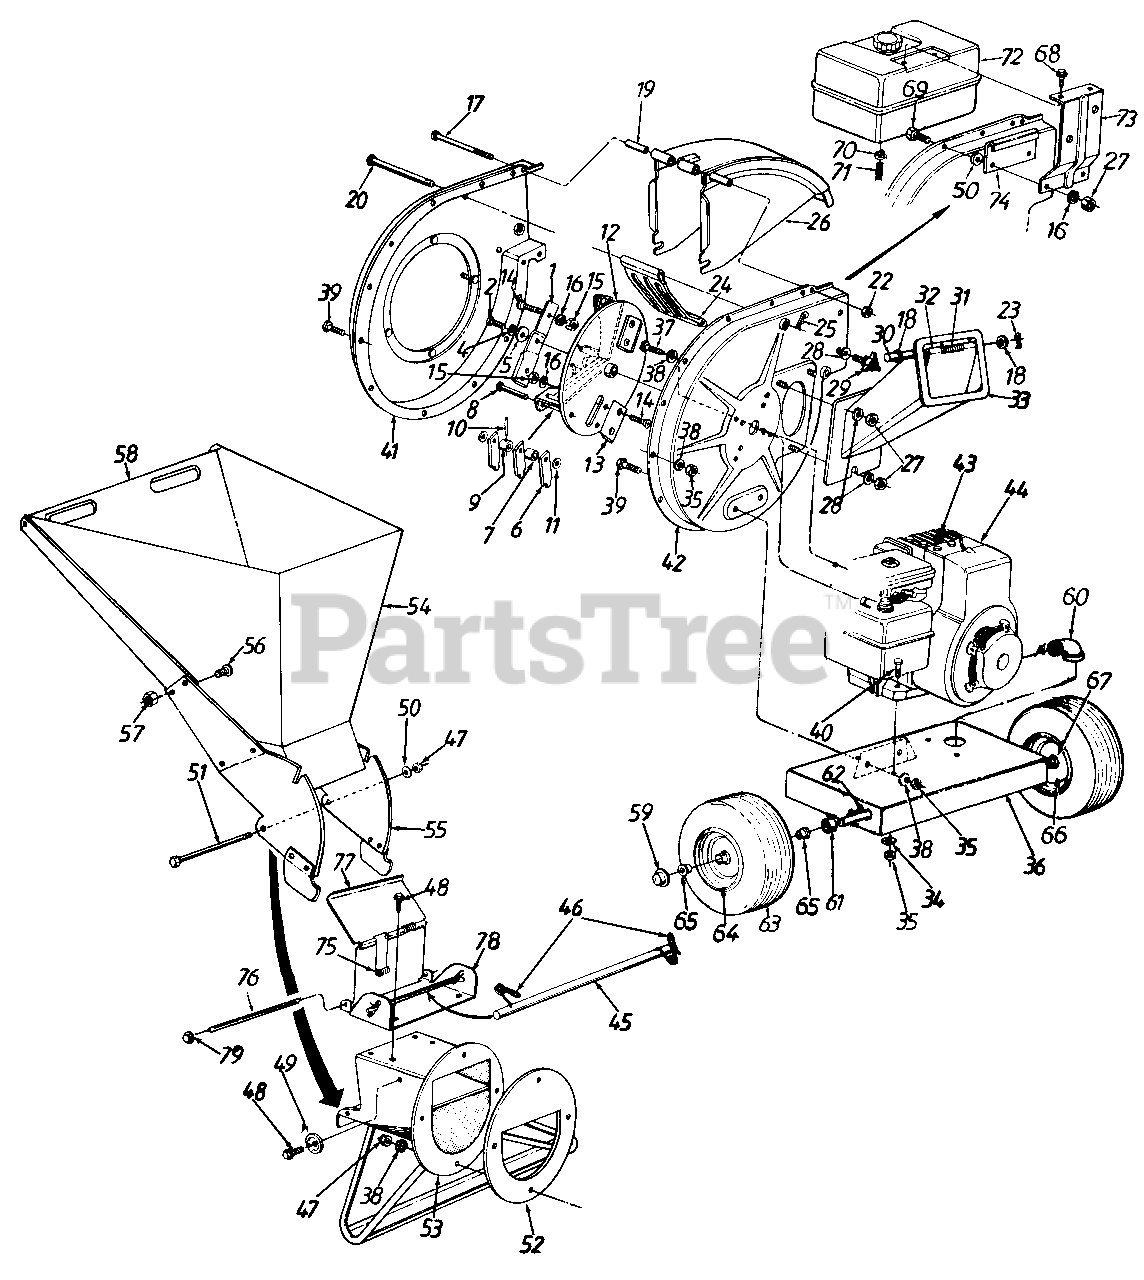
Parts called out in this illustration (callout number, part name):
1	Blade
2	Hex Patch Bolt 3/8-24 x 2.25" (Gr. 8)
4	L-Wash. 3/8" I.D. H.D.
5	Fl-Wash. .406" I.D. x 1.25" O.D. Hdn.
6	Flail
7	Flail Spacer
8	Clevis Pin .496" Dia.
9	Flail Spacer w/.160" Dia. Hole
10	Spring Roll Pin 1.12" Lg.
11	Fl-Wash. .531" I.D. x .94" O.D.
12	Impeller Ass'y. Comp.
13	Chipper Blade
14	Flat Hd. Scr. 5/16-24 x .75" Lg.
15	Hex Top L-Nut 5/16-24 (Gr. 5)
16	L-Wash. 5/16" I.D.
17	Hex Bolt 1/4-20 x 3.75" Lg.
18	Fl-Wash. .281" I.D. x .5" O.D.
19	Chute Hinge Spacer 1.66" Lg.
20	Clevis Pin .5" Dia. x 4.62" Lg.
22	Hex Ctr. L-Nut 1/4-20 Thd.
23	Cotter Pin
25	Internal Cotter Pin 3/8" Dia.
27	Hex Nut 5/16-18 Thd. (Gr. 5)
28	Bell-Wash. .345" I.D. x .88"
29	Hand Knob
30	Chipper Door Rod
31	Torsion Spring 1.14" Lg.
35	Hex Nut 5/16-18 Thd. (Gr. 5)
37	Hex Bolt 5/16-24 x .75" Lg.
38	L-Wash. 5/16" I.D.
39	Hex Bolt 5/16-18 x .75" Lg. (Gr. 5)
40	Hex Bolt 5/16-18 x 1.75" Lg.
44	Engine
45	Release Bar
46	Torsion Spring 1.06" Lg.
47	Elastic Lock Nut 5/16-18 Thd.
48	Hex Wash. Hd. Self-Tap Scr. 5/16-18 x .75" Lg.
49	Stop Washer
50	Fl-Wash. 5/16" I.D.
51	Hex Bolt 5/16-18 x 8.38" Lg.
57	Hex L-Nut 1/4-20 Thd.
60	Drain Elbow (645C)
61	Spacer .64" I.D. x .38" Lg.
62	Shredder Axle
66	Air Valve
67	Grease Fitting
68	Hex Hi-Low Scr. 1/4" x .75" Lg. (650C)
69	Hex Bolt 5/16-18 x .88" Lg. (650C)
70	Hose Clamp (650C)
71	Fuel Line--7" Lg. (650C)
72	Fuel Tank Ass'y. Comp. (650C)
76	Hopper Door Rod
11461B-0498	RAMP SECTI - OLD CUB YELLOW (0498)
11461B-0629	RAMP SECTI - SILVER FLAKE (0629)
11461B-0638	RAMP SECTI - MTD/TROY-BILT RED (0638)
11461B-0662	RAMP SECTI - OYSTER GRAY (0662)
16522B-0498	GUIDE ASSEMBLY-INLET (CUB YELLOW) - OLD CUB YELLOW (0498)
16522B-0637	GUIDE ASSEMBLY-INLET - POWDER BLACK (0637)
16522B-0638	GUIDE ASSEMBLY-INLET - MTD/TROY-BILT RED (0638)
16522B-0662	GUIDE ASSEMBLY-INLET (OYSTER GRAY) - OYSTER GRAY (0662)
16524B-0498	GUIDE ASSEMBLY-UPR (CUB YELLOW) - OLD CUB YELLOW (0498)
16524B-0638	GUIDE ASSEMBLY-UPR (MTD RED) - MTD/TROY-BILT RED (0638)
16524B-0648	GUIDE ASSEMBLY-UPR (TECH GRAY) - TECH GRAY (0648)
16524B-0662	GUIDE ASSEMBLY-UPR (OYSTER GRAY) - OYSTER GRAY (0662)
